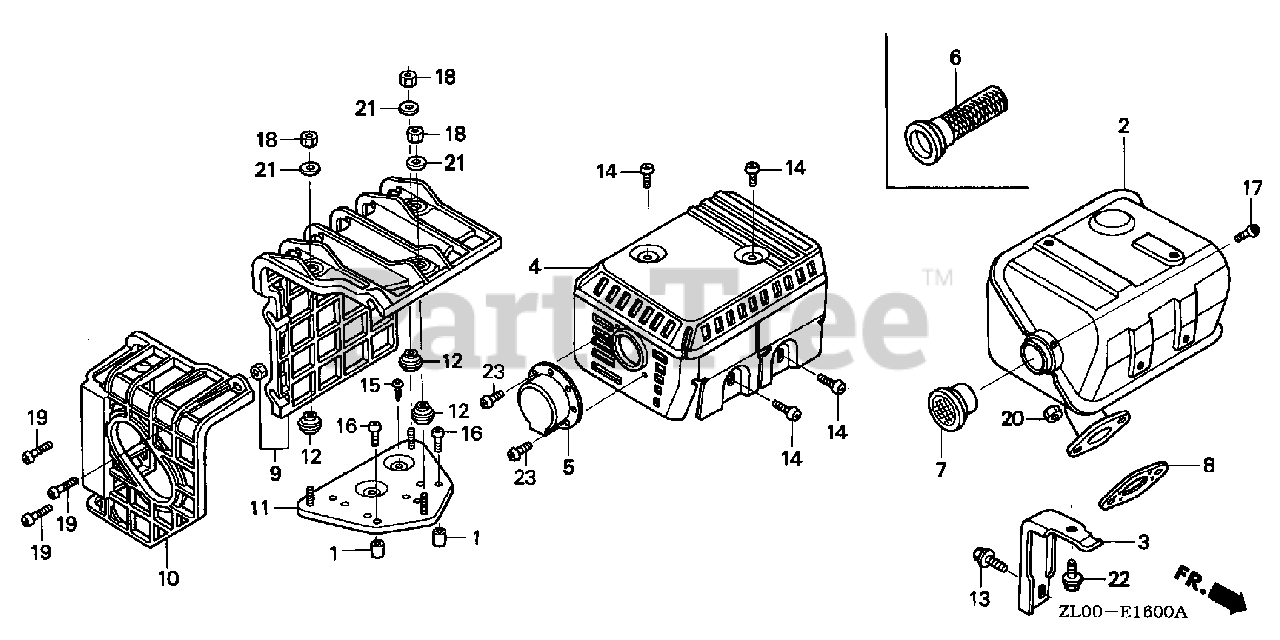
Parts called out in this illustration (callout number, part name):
2	MUFFLER
2	MUFFLER (ARRESTER)
3	STAY, MUFFLER
4	PROTECTOR, MUFFLER
6	ARRESTER, SPARK
8	GASKET, MUFFLER
13	BOLT, FLANGE (6X13)
14	SCREW, TAPPING (5X8)
17	SCREW, TAPPING (4X6)
20	NUT, HEX. (8MM)
22	BOLT, FLANGE (6X12)
